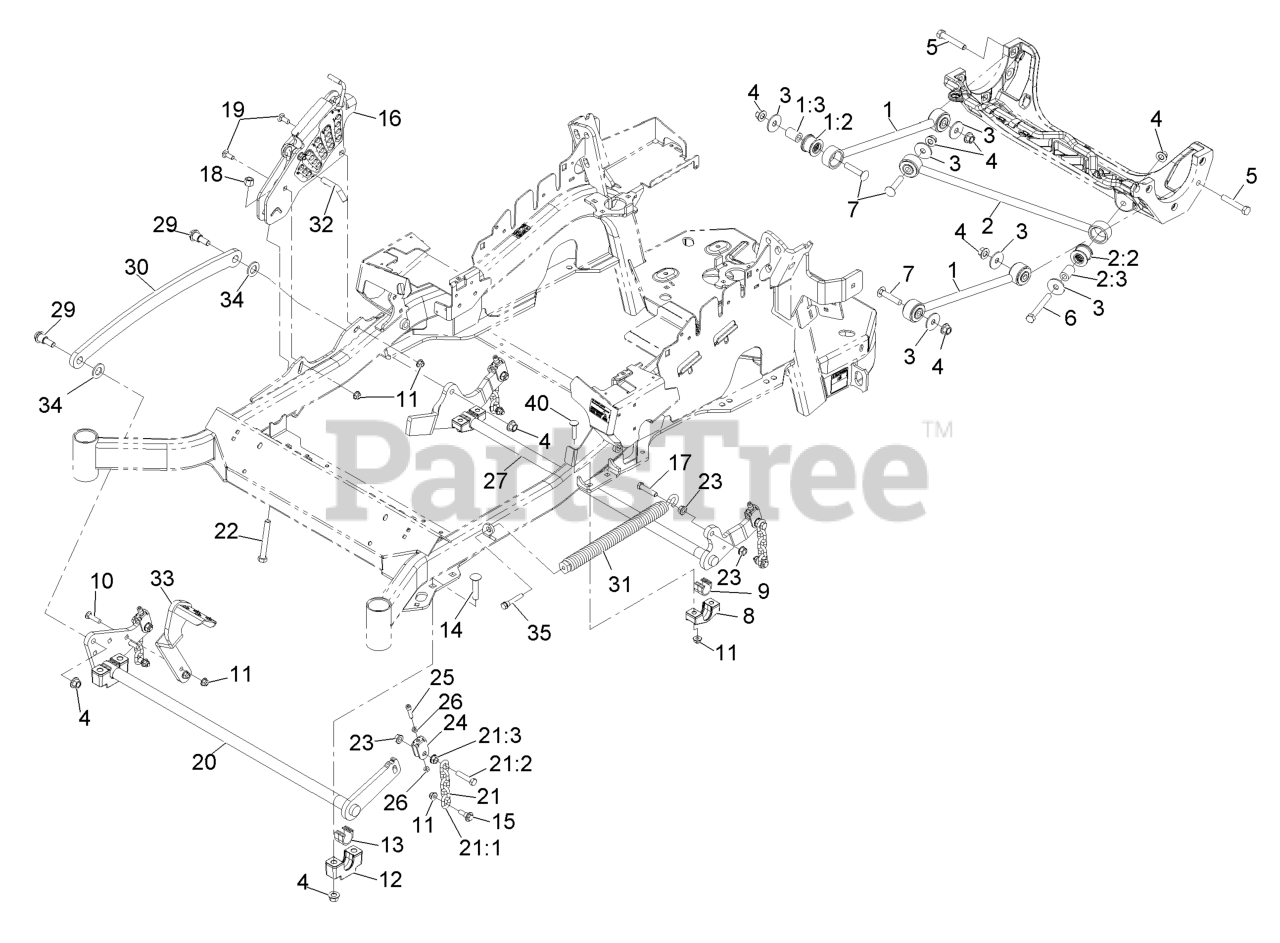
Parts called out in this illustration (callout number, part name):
1	LONG STRUT ASM
1:2	BUSHING-SUSPENSION, RUBBER
2	PANHARD ROD ASM
2:2	BUSHING-SUSPENSION, RUBBER
3	WASHER-THRUST
4	Nut-Lock 1/2-13
5	SCREW-HH
6	SCREW-HH
7	SCREW-CARR
9	BEARING-CROSS SHAFT, REAR
10	SCREW-CARR
11	NUT-HF, NI
12	SUPPORT-CROSS SHAFT, BEARING
13	BEARING-CROSS SHAFT, FRON
14	Bolt-Carriage 1/2-13 X 2 1/2 Spl Neck
15	SCREW-SHOULDER, HHF
16	HOC ASM
17	SCREW-HH
18	NUT-LOCK, NI
19	BOLT-CARR
21	DECK LIFT CHAIN ASM
21:1	CHAIN-LIFT, DECK
21:2	SCREW-HH
22	BOLT-TAP
24	YOKE-ADJUST, DECK
25	SCREW-HSH
26	NUT-JAM
27	LIFT-DECK, REAR
29	SCREW-SHOULDER, HHF 1/2-13 X 1.12
30	LINK-LIFT, DECK
31	SPRING-EXTENSION
32	PIN-HOC
33	LEVER-FOOT
34	WASHER-FLAT
35	BOLT-SHOULDER
40	SCREW-CARR
